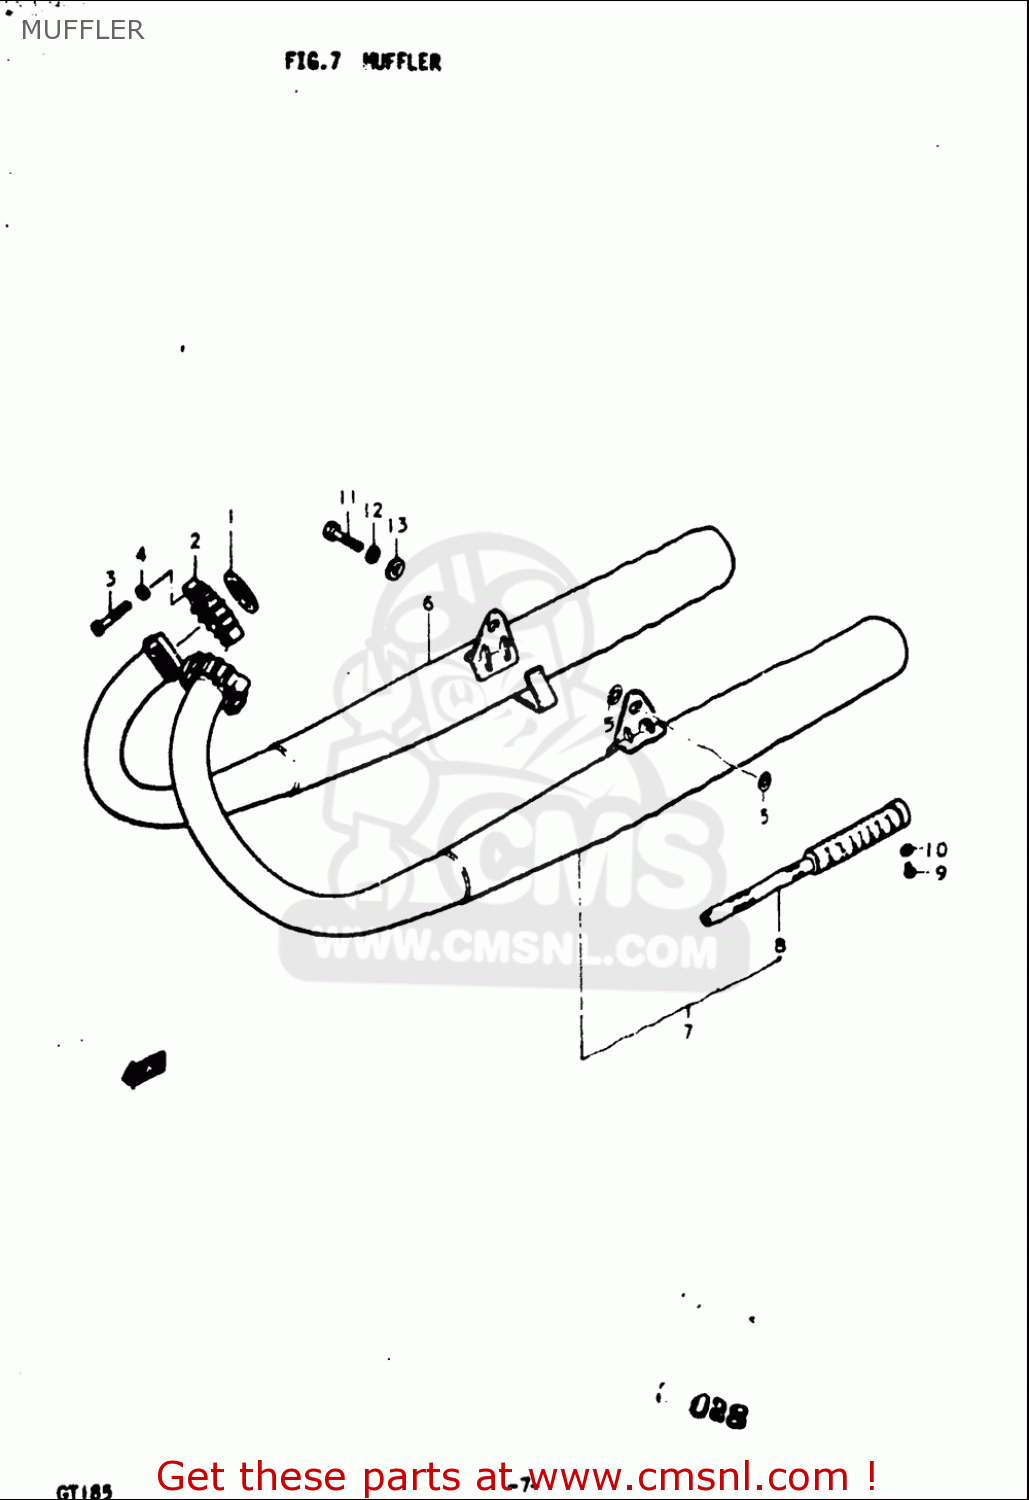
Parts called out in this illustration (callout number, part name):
1	GASKET,EXHAUST (NAS)
3	BOLT
4	WASHER,LOCK
5	WASHER
6	MUFFLER,RIGHT
7	MUFFLER,LEFT
8	PIPE,BAFFLE
9	SCREW(5X6)
10	WASHER,LOCK
11	BOLT
12	WASHER,LOCK
13	WASHER
